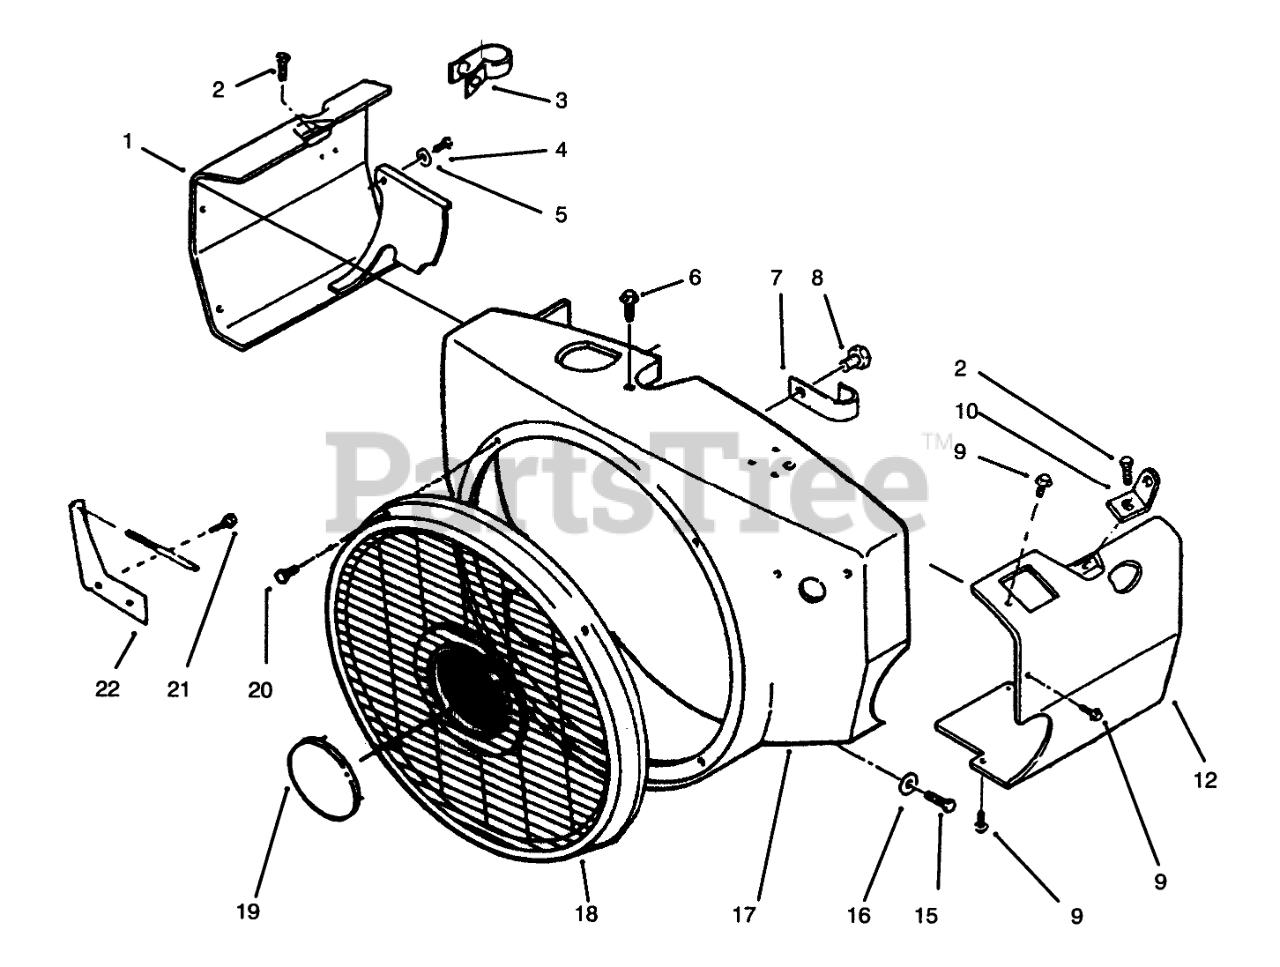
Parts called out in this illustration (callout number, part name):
1	LH AIR CYLINDER HSG
2	SCREW-HWH
3	WIRE CLAMP
4	SCREW-HH
5	WASHER-FLAT
6	HEX HD CAPSCREW
7	CLIP-WIRE
8	SCREW-HWH
9	SCREW-HWH
10	BRACKET-LIFTING
12	RH AIR CYLINDER HSG
15	SCREW-HH
16	WASHER-FLAT
17	BLOWER-HOUSING
18	GUARD-STATIONARY
19	NAME-PLATE TORO LOGO
20	SCREW-PAN HEAD
21	SCREW-HWH
22	BRACKET
